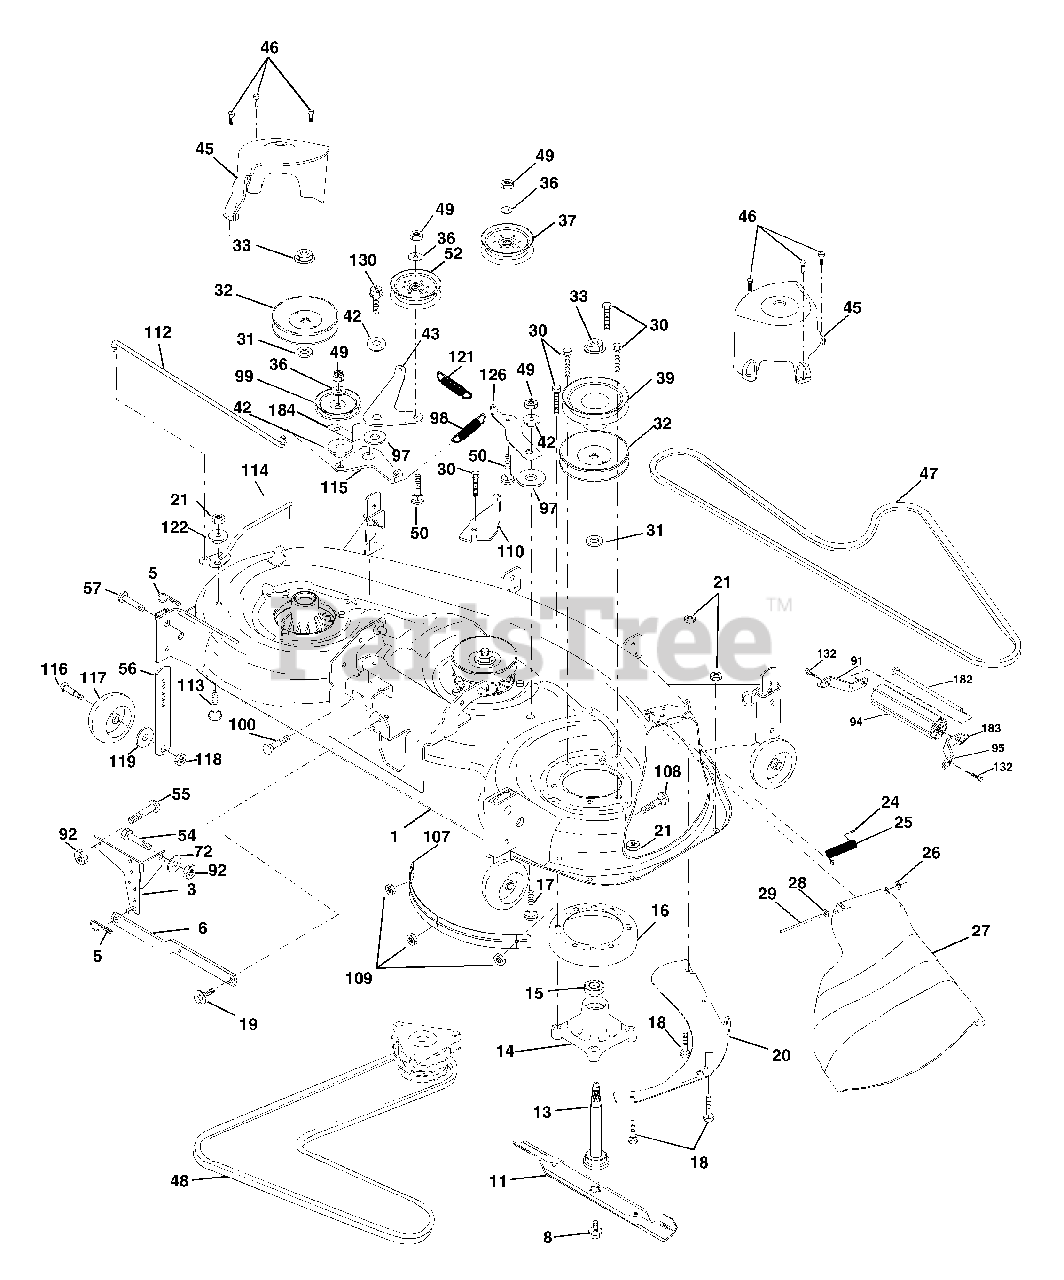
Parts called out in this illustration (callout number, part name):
1	Deck Weldment Mower 48
3	Bracket Asm., Sway Bar
5	Retainer Spring
6	Sway Bar Deck
8	Bolt, 7/16 Asm. Blade
13	Shaft Asm. greaseable
14	Housing Mandrel 48"
15	Bearing, Ball, Mandrel
16	Stripper, Mower
17	Bolt Rdhd Sq Neck 3/8-16 x 1.25
18	Bolt, Carriage 5/16-18 x 5/8
19	Bolt, Hex Head, Shoulder 5/16-18
20	Baffle, Vortex Mower
21	Nut, Crownlock 5/16-18 UNC
24	Cap, Sleeve
25	Spring, Torsion
27	Shield, Deflector Mower
28	Washer 11/32 x 5/8 x 16 Ga.
29	Rod, Hinge
30	Screw, Thdroll, Washer Head
31	Washer, Spacer Mower Vented
32	Pulley, Mandrel
33	Nut, Flg. Top Lock Cntr. 9/16
36	Washer 13/32 x 13/16 x 16 Ga.
37	Pulley, Idler, Flat
39	Pulley, Idler, Driven
42	Spacer, Retainer
43	Arm, Idler Secondary
45	Cover, Mandrel Deck
46	Screw, Thdroll. 1/4-20 x 5/8
47	V-Belt, Mower, Secondary
48	V-Belt, Mower, Primary
49	Nut, Crownlock 3/8-16 UNC
50	Bolt, Carriage 3/8-16 x 1-1/2 Gr. 5
52	Pulley Idler Flat 46 Pri. Drive
54	Bolt Fin Hex 3/8-16 x 1
55	Bolt Rdhd Sqnk 3/8-16 x 1
56	Bar Pnt Adjusting Wheel Gauge
57	Pin Head Rivet
72	Washer 13/32 x 13/16 x 12
91	Bracket, Asm Noseroller, LH 48
92	Nut Lock Hex w/Ins 3/8-16
94	Roller, Nose 48"
95	Bracket, Asm Noseroller RH 48
97	Washer Hardened
98	Spring Primary Drive
99	Pulley Idler "V"
100	Bolt RDHD Sqnk 3/8-16 Unc x 2
107	Baffle Vac Edge Mower
108	Bolt Rdhd 1/4-20 x 1/2
109	Nut Crownlock 1/4-20
110	Arm Spring Secondary
112	Link Tension Relief Lever
113	Bolt Carr. 5/16-18 x 1
114	Tension Asm Relief Lever
115	Arm Spring Tension Relief
116	Bolt, Shoulder
117	Gauge Wheel
118	Nut, Centerlock 3/8-16 UNC
119	Washer 3/8 x 7/8 x 14 Ga.
121	Spring Secondary Drive
122	Bushing Pivot Tension Relief
126	Arm, Idler, Primary Deck
130	Screw 3/8-16 x 1.0
132	Screw 3/8-16 x .75
182	Rod Roller Nose
183	Retainer Spring
184	Keeper Belt Idler
